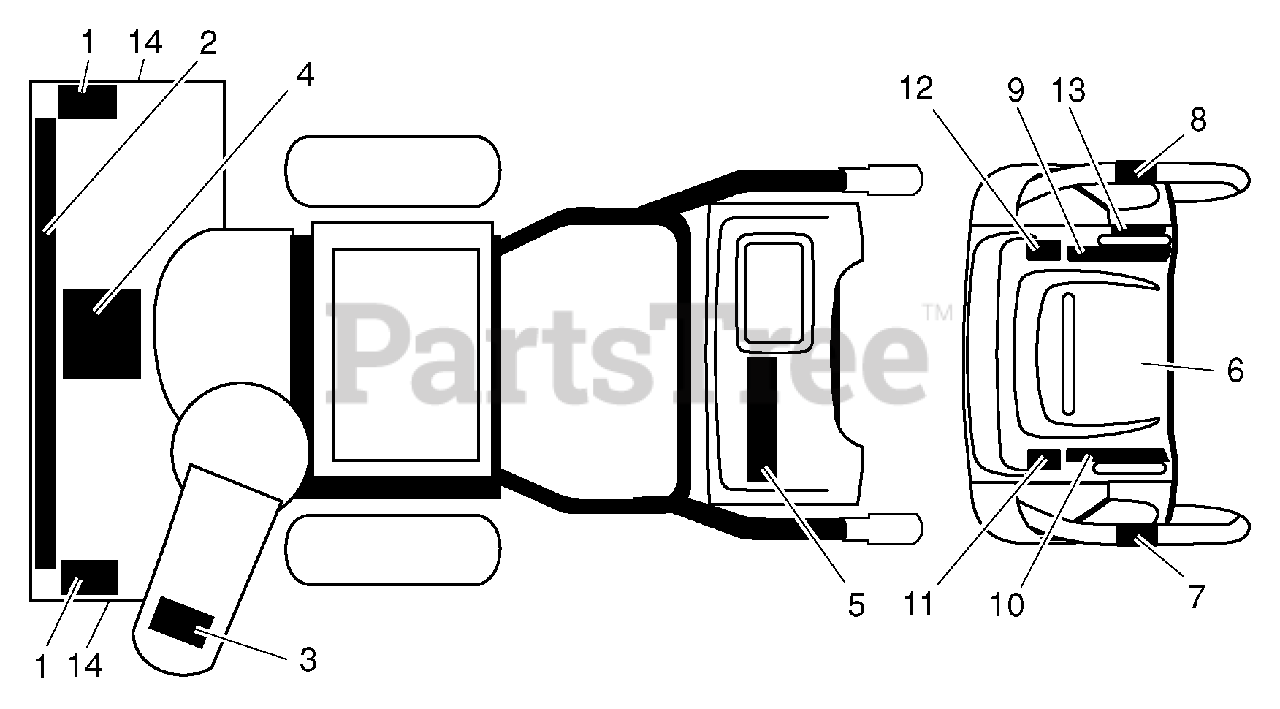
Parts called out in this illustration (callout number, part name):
1	Decal, Danger
2	Decal, Husqvarna
3	Decal, Danger, Deflector
4	Decal, Danger
5	Decal, Husqvarna, 1330SBE
6	Decal, Instruction
7	Decal, Traction Lever
8	Decal, Auger Lever
9	Decal, Speed Control
10	Decal, Remote Deflector
11	Decal, LH Trigger
12	Decal, RH Trigger
13	Decal, Console, Hydro
14	Decal, Husqvarna, Crown
